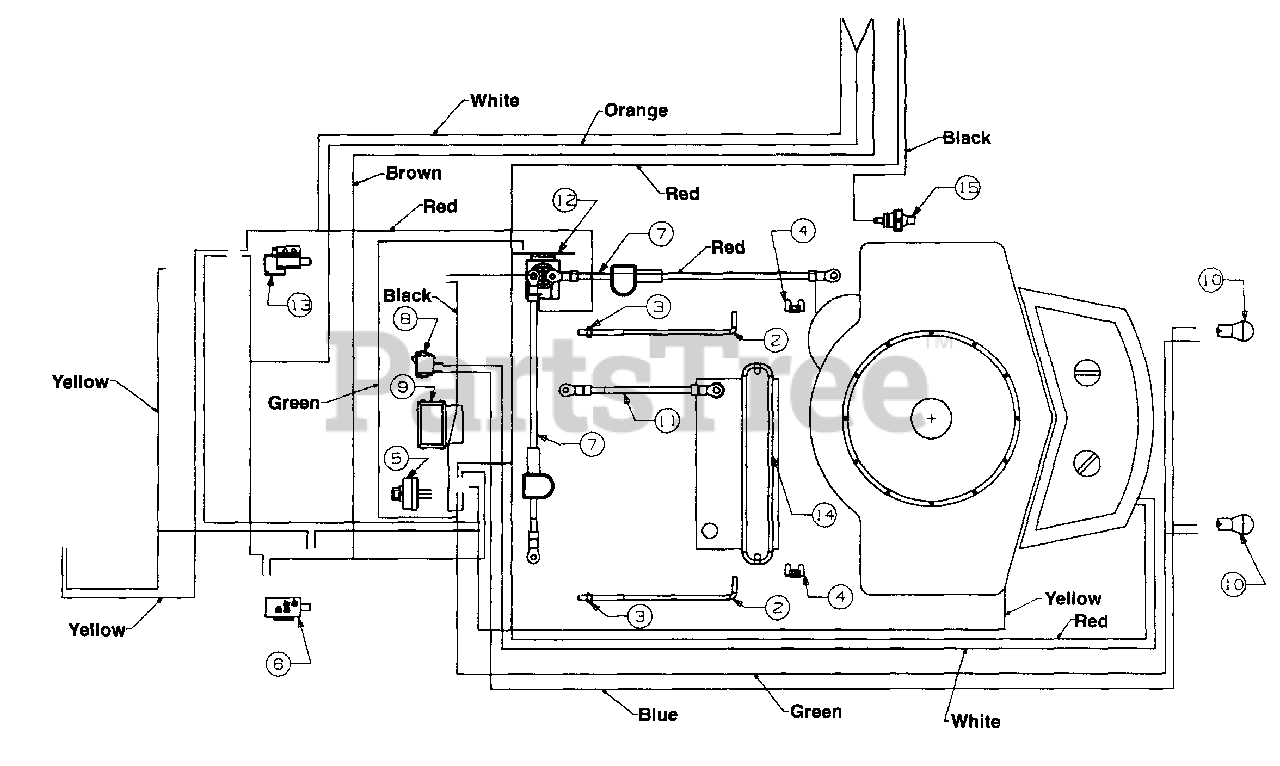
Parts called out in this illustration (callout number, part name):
2	Battery Hold Down Rod
3	Hex L-Nut 1/4-20 Thd.
4	Wing Nut 1/4-20 Thd.
5	Ignition Switch
6	Safety Switch (PTO)
7	Wire w/Boot 14" Lg.
8	Light Switch
9	Ammeter
10	Bulb (Headlight)
11	Wire 7.5" Lg.
12	Solenoid
13	Safety Switch (Clutch)
14	Battery Cover
15	Oil Pressure Switch
